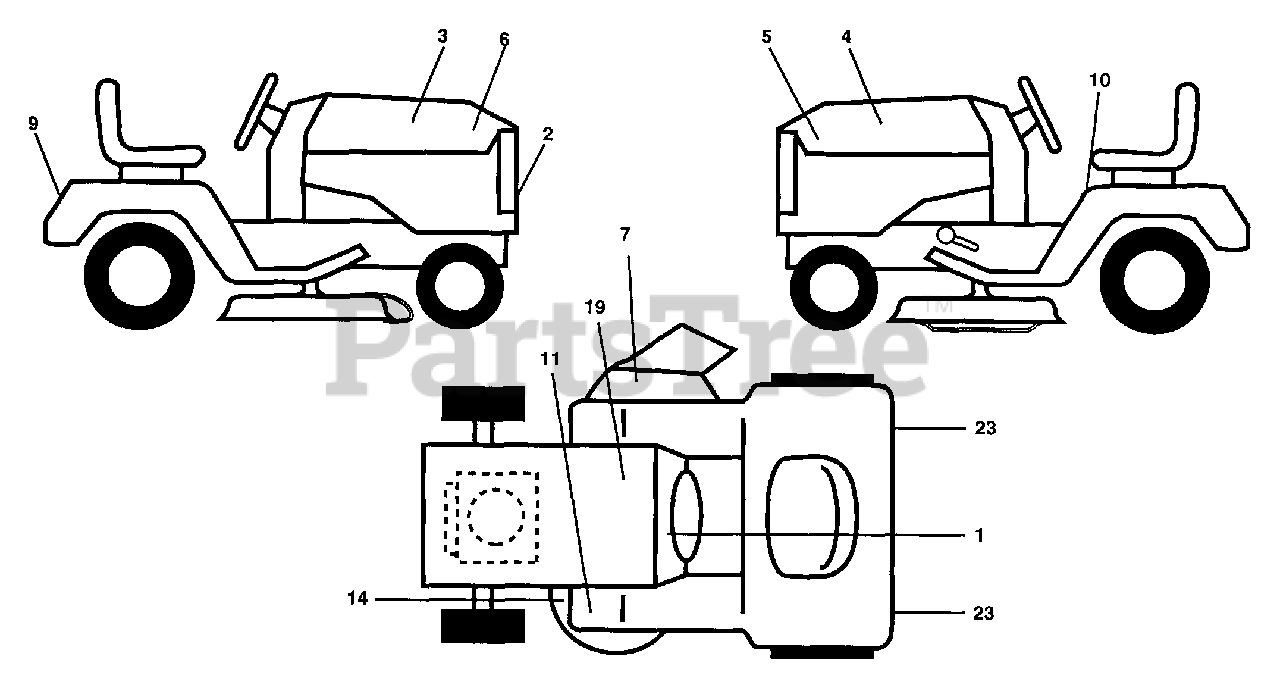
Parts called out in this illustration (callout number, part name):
1	Decal, Operating Instruction
2	Decal, Grille Husqvarna "H" Logo
3	Decal, Hood, RH
4	Decal, Hood, LH
5	Decal, Insert Hood LH GT200 6Sp
6	Decal, Insert Hood RH GT200 6Sp
7	Decal, Warning Multi-Language
9	Decal, Fender
10	Decal, Caution
11	Decal, Clutch/Brake
14	Decal, V-Belt Schematic
19	Decal, Battery
23	Reflector, Taillight
